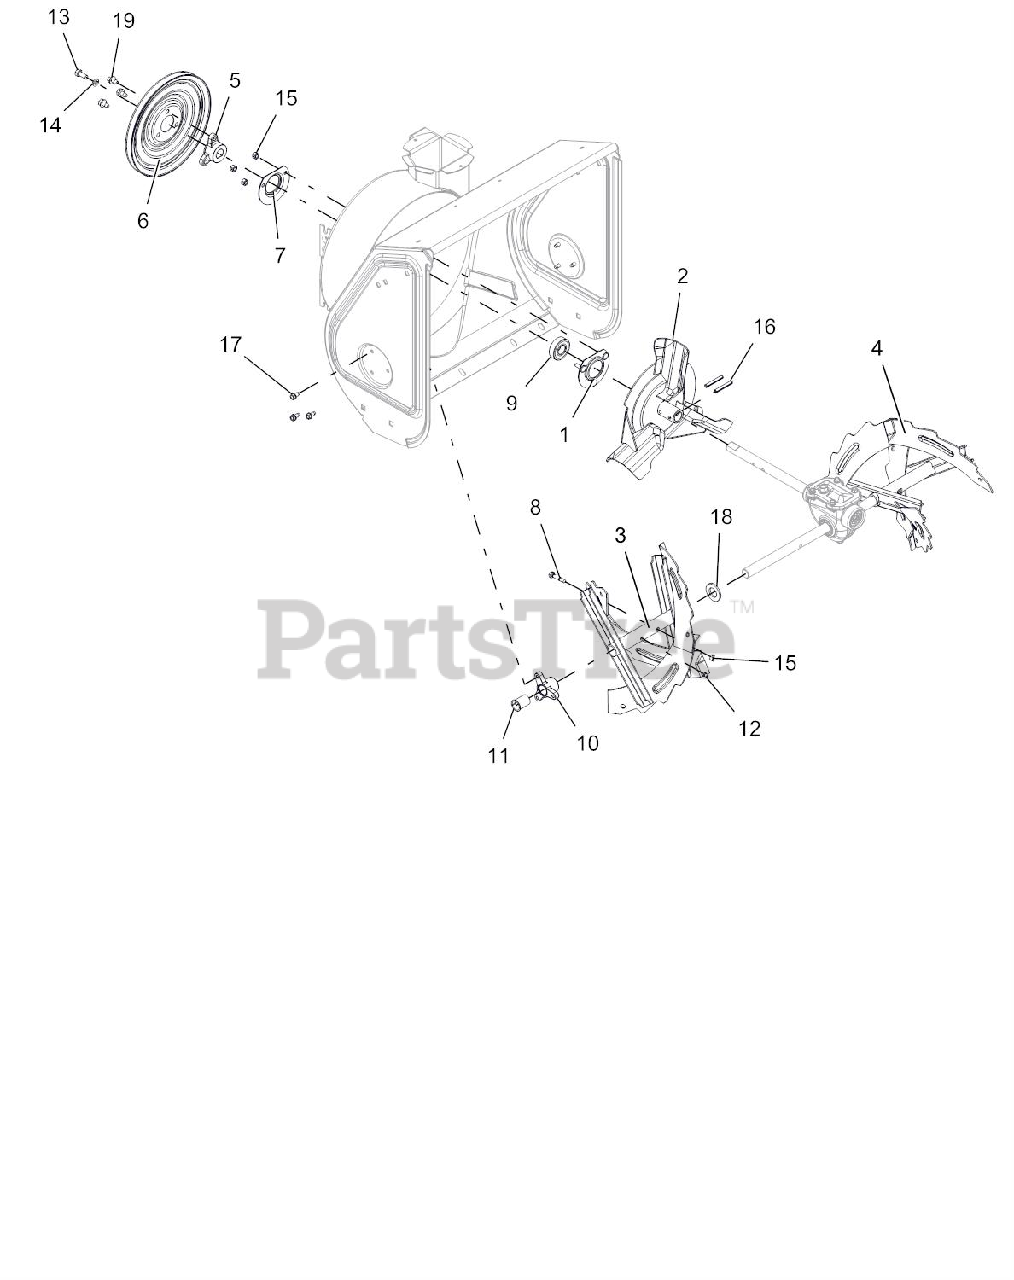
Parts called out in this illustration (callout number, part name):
1	BEARING FLANGE
2	IMPELLER, COMPACT 12" 3-BLADE
3	AUGER, 20" RH, BLK SERR W/ZERK
4	AUGER, LH 20", BLK SERR W/ZERK
5	PULLEY HUB, BOLT-ON D-BORE .75
6	PULLEY,SPIN FORM SINGLE GROOVE
7	BEARING FLANGE
8	SHEAR BOLT WITH NUT
9	BRG-BALL .750X1.750X.50
10	BUSHING, RAKE SHAFT .75"
11	BSHG-FLG SPLIT NYLINER .75"ID
12	ZERK,FITTING .25X.125 DRIVE IN
13	BLT-HEX .31-24X.75 YWZC GR5
14	WSHR-LK .312X.097 HVY YWZC
15	@NUT-LK-CTR .25-20 YWZC
16	PIN-ROLL .250X1.75
17	SCR-TAP .25-20X.50 HWH TR YWZ
18	@WSHR-FL-STL.812X1.50X.135YWZC
19	@SCR-TAP .31-18X.50 HWH TR YWZ
